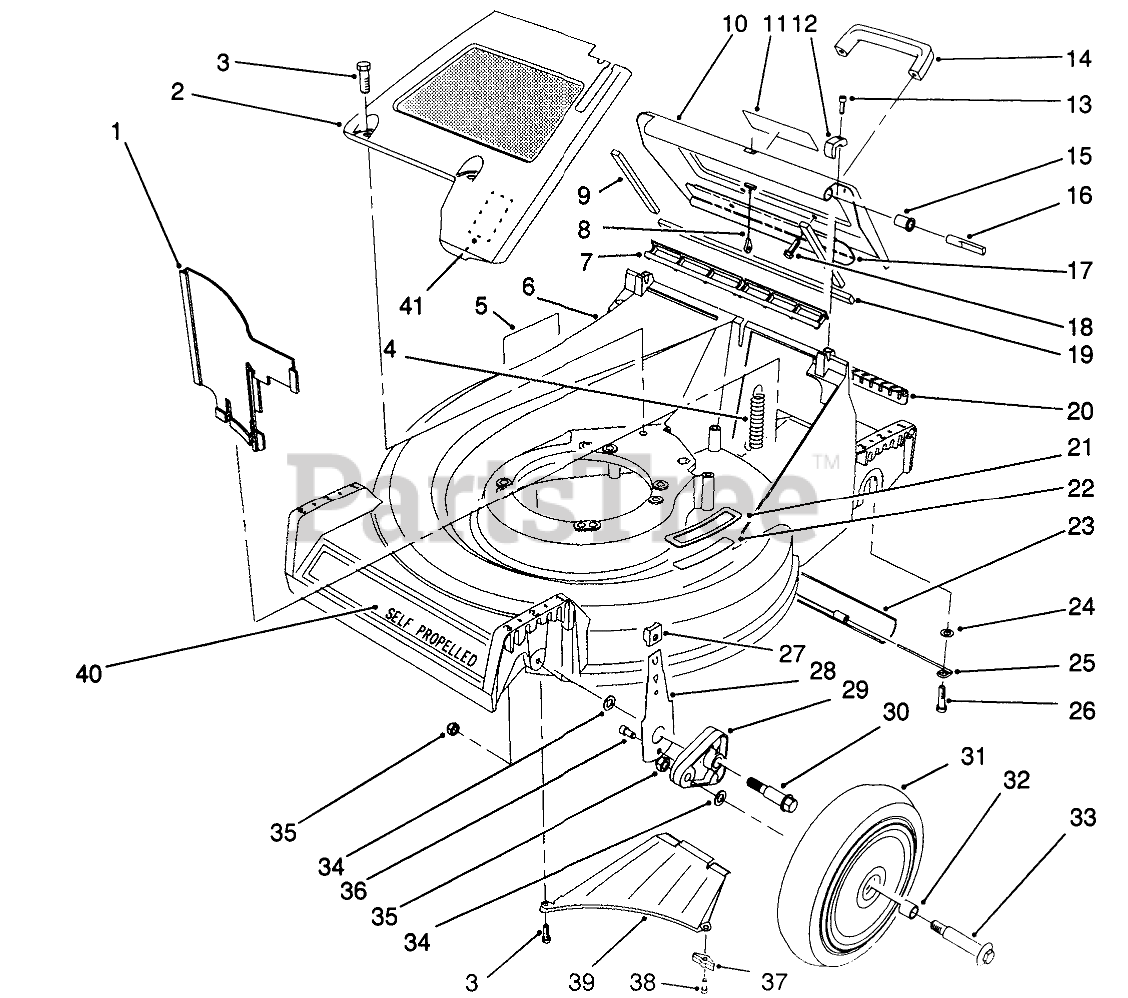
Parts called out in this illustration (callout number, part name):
1	PANEL-VERTICAL
2	PaneI-Screen
3	SCREW-HWHTF
4	EXTENSION-SPRING
5	DECAL-DANGER
6	21" Housing Assembly (Incl. Ref. #5, 21-22)
7	DOOR SEAL
8	DOOR CABLE
9	DOOR SIDE SEAL
10	Door-Discharge (Incl. Ref. #9, 11, 17 & 19)
11	DECAL - WARNING
12	HINGE CLAMP
13	SCREW-HSH
14	HANDLE-DOOR
15	DOOR BUSHING
16	HINGE PIN
17	DOOR - BRACE
18	SCREW-HWH
19	DOOR END SEAL
20	ACCESS COVER
21	STEP PAD
22	STEP PAD DECAL
23	TRAILING SHIELD
24	WASHER-PLAIN
25	SHIELD HANGER
26	SCREW-SHOULDER
27	KNOB-ARM
28	FRONT SPRING ARM ASM
29	ARM-PIVOT, FRONT
30	BOLT-SHOULDER
31	Wheel & Tire Assembly (Incl. Ref. #30)
32	BUSHING
33	WHEEL BOLT
34	WASHER
35	NUT-LOCK
36	SCREW-HSH, THREAD FORMING
37	Bracket-Discharge
38	SCREW-HWHTF
39	Ramp Discharge
40	DECAL - 21 SP
41	DECAL - BBC ADJUST
